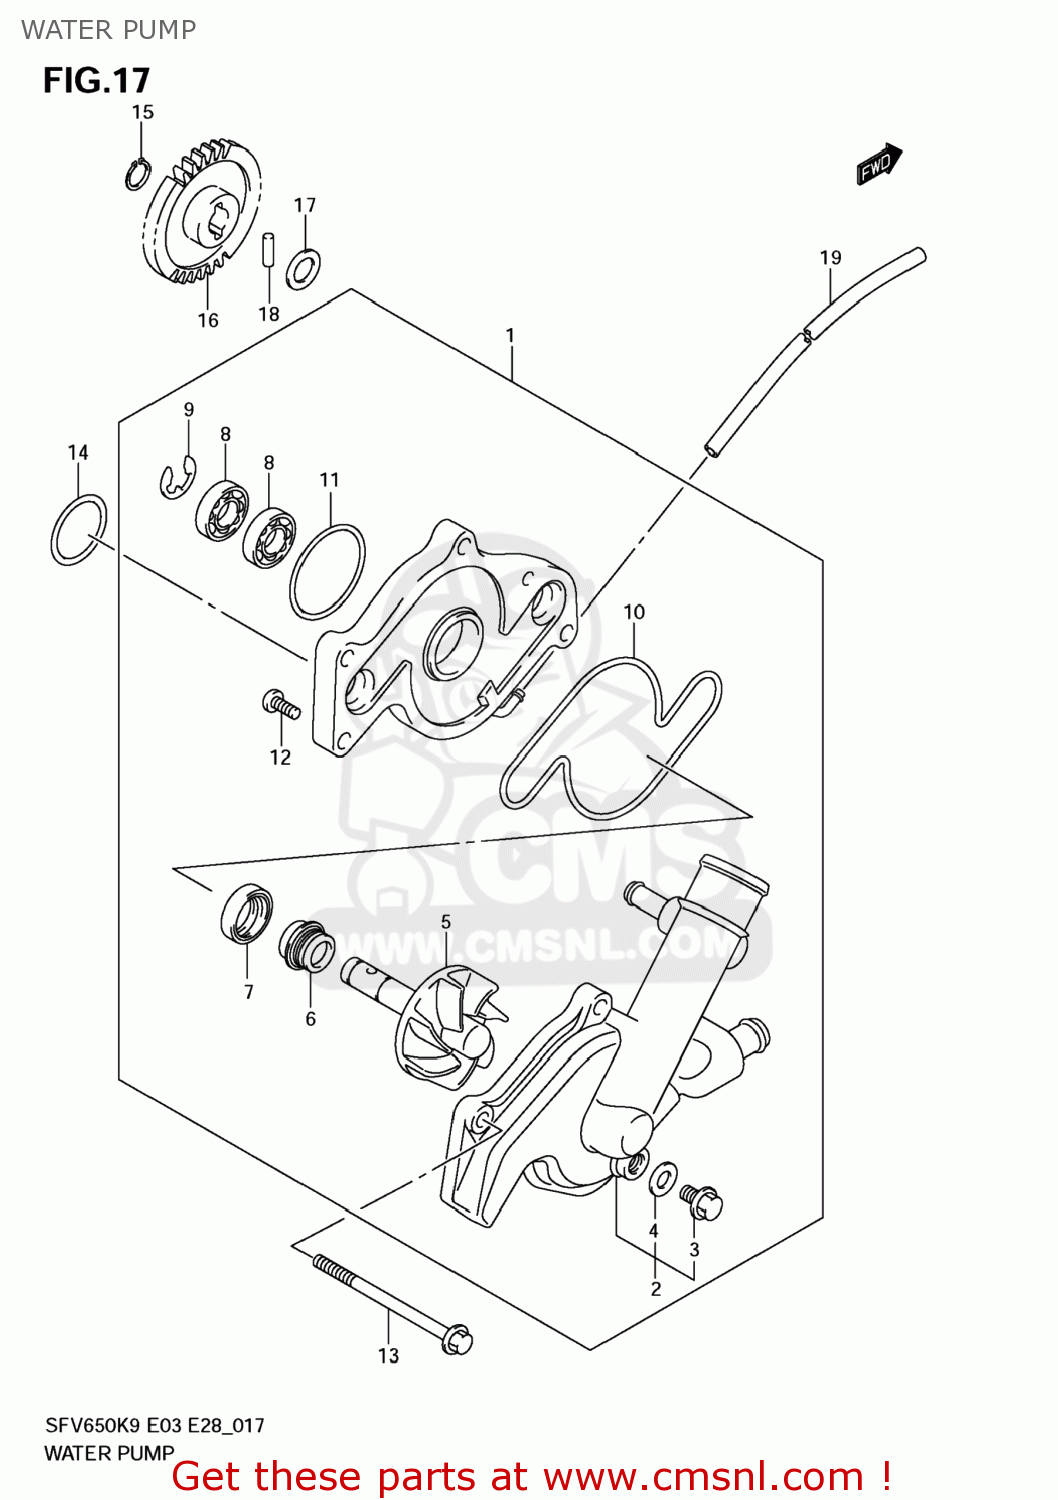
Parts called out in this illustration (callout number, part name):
1	PUMP ASSY,WATER
2	CASE,WATER PUMP
3	BOLT,DRAIN
4	GASKET 8.2X14X1 (NAS)
5	IMPELLER/SHAFT
6	SEAL,MECHANICAL
7	SEAL,OIL
8	BEARING
9	E RING
10	O RING
11	O RING,WATER PUMP HOLDER
12	SCREW
13	BOLT(6X70)
14	O RING(D:2.4,ID:21.8)
15	CIRCLIP
16	GEAR,WATER PUMP DRIVEN
17	SHIM(10X18X0.5)
18	ROLLER(4X13.8)
19	HOSE(3.5X6.5X600)
